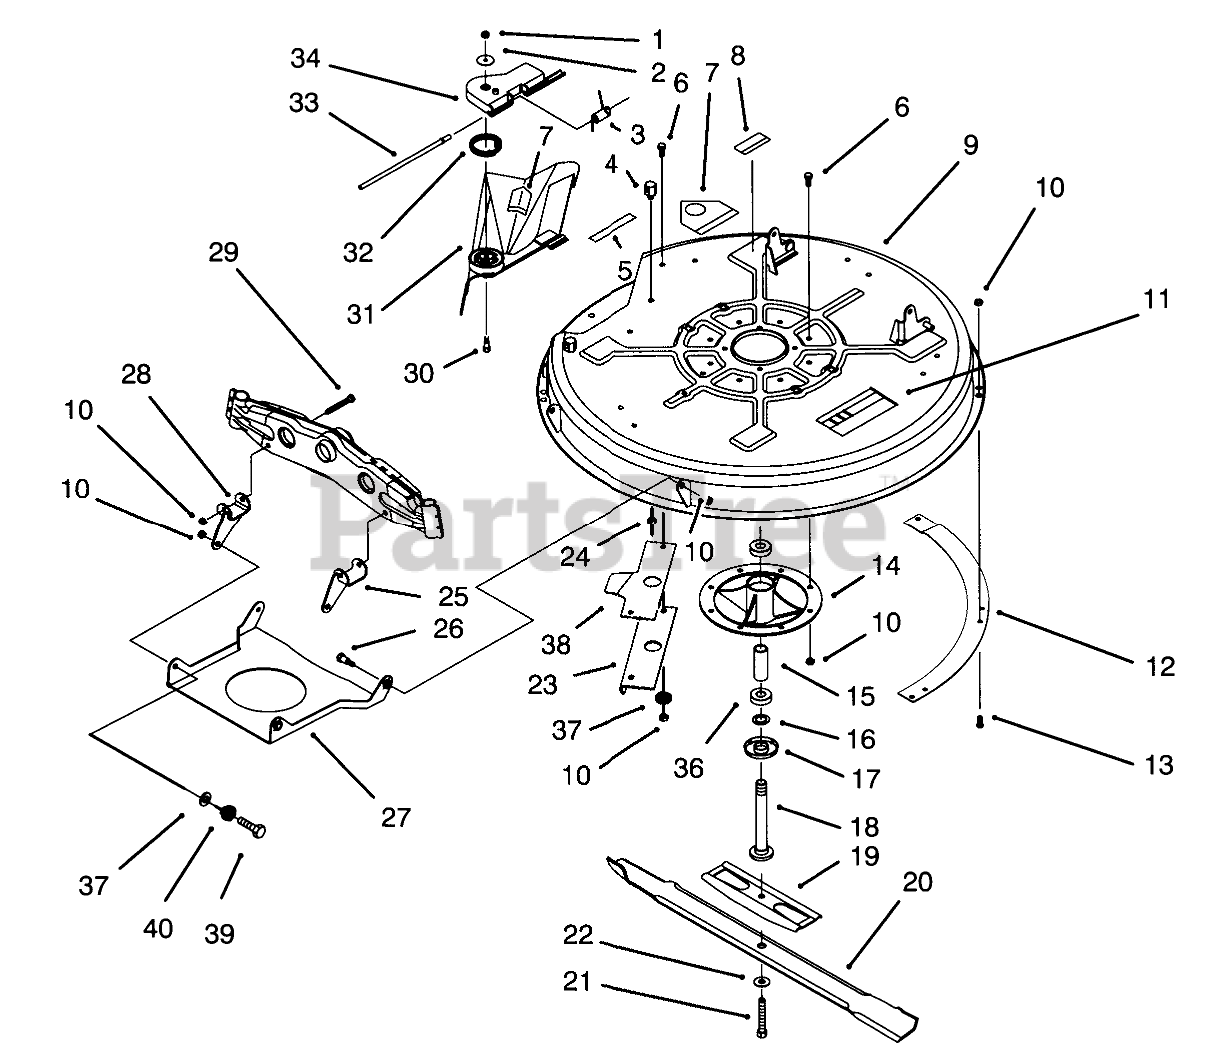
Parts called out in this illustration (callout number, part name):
1	NUT-LOCK, NI
2	WASHER-FLAT
3	SPRING-TORSION
4	POST-PIVOT
5	DECAL-DANGER, DEFLECTOR
6	SCREW-HH
7	DECAL-DANGER
8	DECAL-WARNING
9	Cutter Deck-32"
10	NUT-LOCK, NI
11	DECAL-DANGER, THROWN OBJECT
12	Ring-Wet Grass (Model No. 71200 Only)
13	SCREW-PPH
14	SPINDLE
15	SPACER-BEARING
16	SPACER-HARDNED
17	SHIELD-BEARING
18	SHAFT-SPINDLE
19	STIFFENER
20	Blade
21	SCREW-HH
22	WASHER-BELLEVILLE
23	Baffle Deck
24	NUT-LOCK, NI
25	Bracket-L.H.
26	BOLT-SHOULDER
27	Pan-Front Deck Susp.
28	Bracket-R.H.
29	SCREW-HH
30	Bolt-Shoulder
31	Deflector Assembly (Incl. Ref. #7)
32	SPRING-TORSION
33	ROD-HINGE, DEFLECTOR
34	PIVOT-HINGE, DEFLECTOR
36	BEARING-BALL
37	WASHER-PLAIN
38	Ramp-Deflector
39	SCREW-HH
